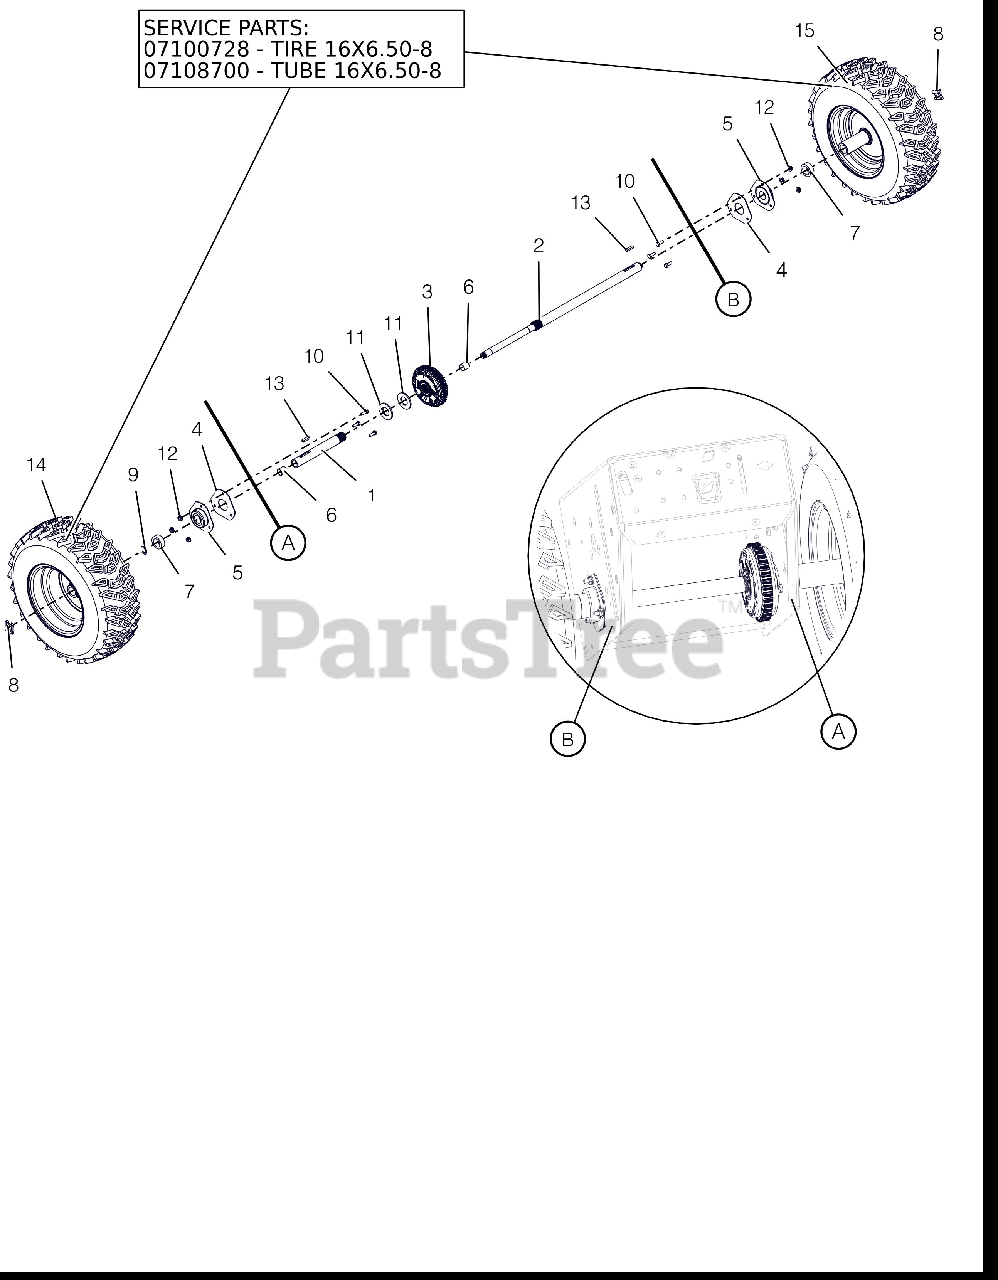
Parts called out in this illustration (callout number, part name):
1	AXLE, SHORT-AUTO W/BUSHINGS
2	AXLE, LONG-PRO AUTO DIFF
3	DIFFERENTIAL, AUTOMATIC
4	PLATE, BEARING SPACER
5	BRG-FLG 1.003/1.000 3 BOLT
6	BSHG-SLV .706X.764X.75 BRZ
7	SPACER, PRO AXLE BEARING
8	CLIP, SNAP .625 DIA
9	RG-RTNG-EXT .625X.042
10	@BLT-HEX .25-20X.75 GR5 YWZC
11	WSHR-FL-STL- 1.062X2.0X.134 YZ
12	@NUT-LK-CTR-FLG .25-20 YWZC
13	KEY-RECT .25X.188X1.00
14	TIRE/WHEEL,RH 16X6.5-8 DIFF T2
14	TIRE, 16X6.50-8 K478
14	TUBE
15	TIRE/WHEEL,LH 16X6.5-8 DIFF T2
